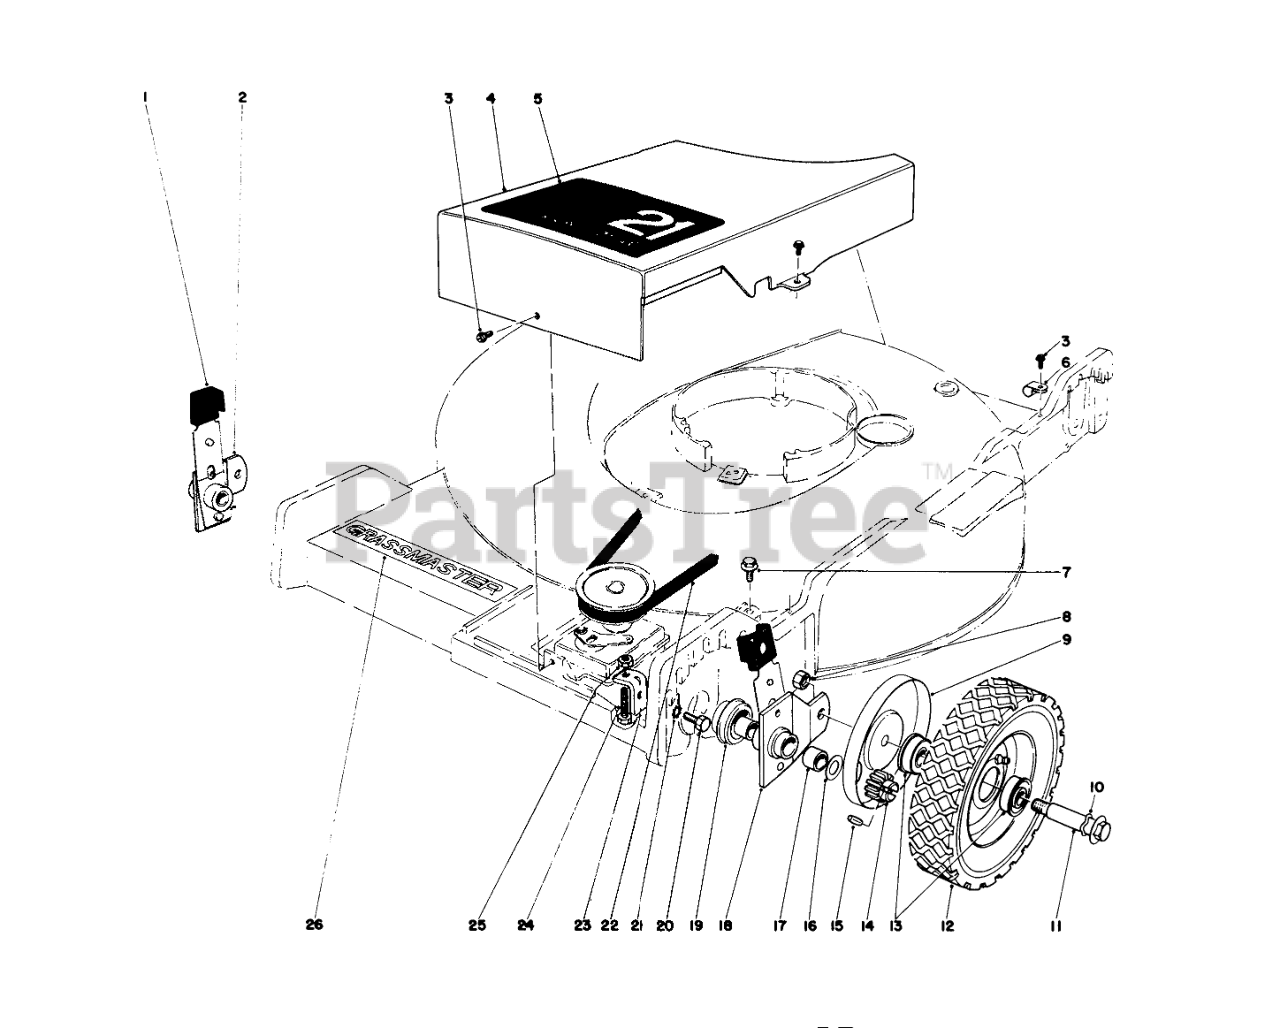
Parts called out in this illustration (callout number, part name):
1	KNOB-ARM
2	Pivot Arm (Incl. Ref. #17)
3	SCREW
4	Belt Cover
5	Decal Belt Cover
6	CLAMP-NYLON
7	SCREW-HWHTF
8	Nut
9	WHEEL COVER
10	SPRING WASHER
11	WHEEL BOLT
12	Wheel & Tire Assembly (Incl. Ref. #13)
13	BEARING-BALL
14	Pinion
15	PIN-GROOVED
16	WASHER-THRUST
17	BUSHING
18	Pivot Arm (Incl. Ref. #17)
19	End Cap
20	SCREW-HH
21	WASHER-LOCK
22	V-BELT
23	Bracket-Gear Box
24	SCREW
25	NUT-LOCK
26	Decal Grassmaster
